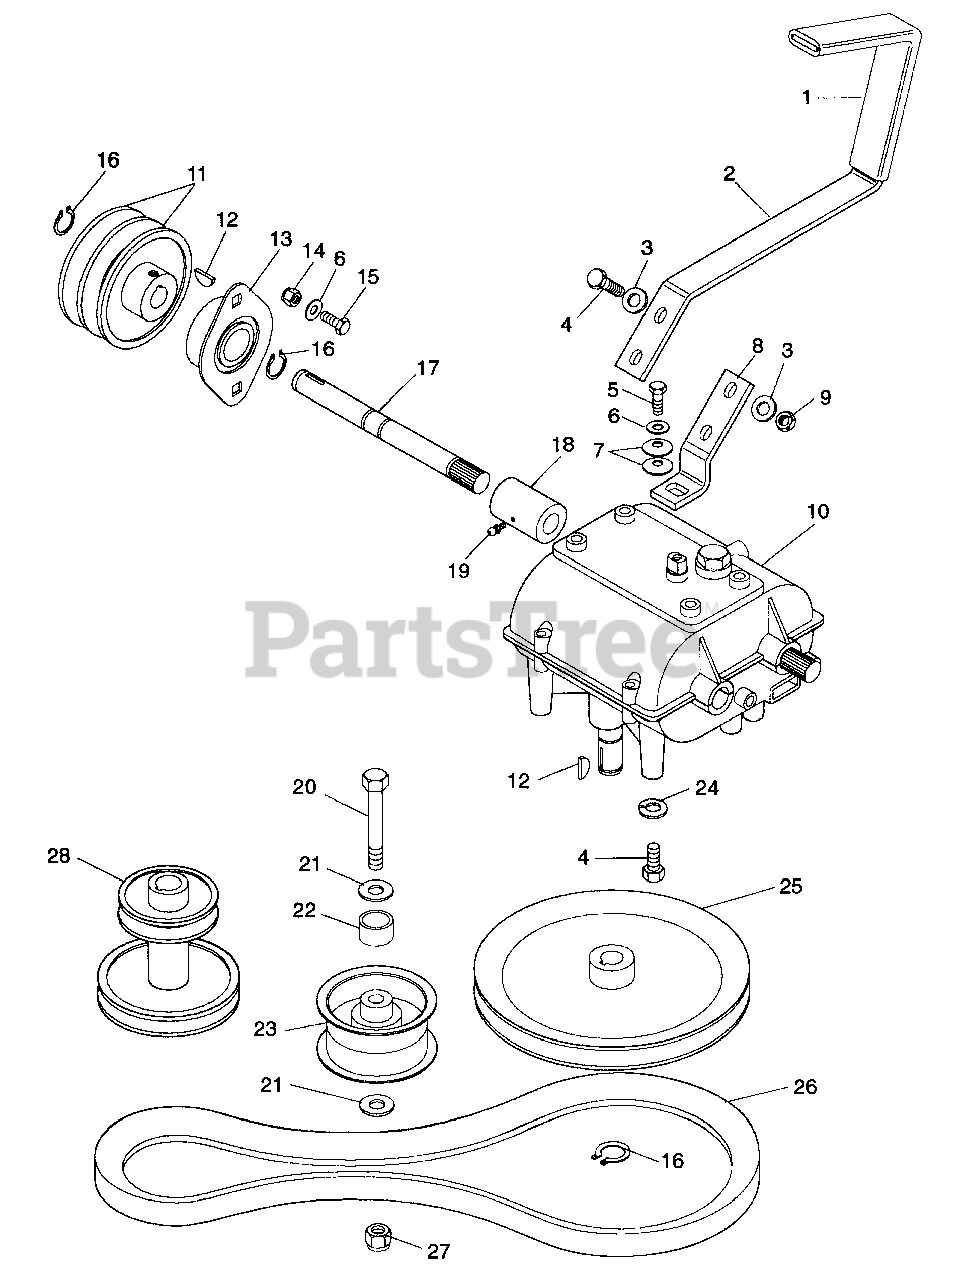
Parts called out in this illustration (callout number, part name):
1	Grip
2	Lever, Transmission Shift
3	Washer-Flat-Steel .344 x .688 x .065
4	Bolt-Hex .31-18 x 1.00 Grade 5
5	Bolt-Hex .25-28 x .75 Grade 8
6	Washer-Flat-Steel .281 x .620 x .065
7	Washer, Belleville
8	Arm, Transmission Shift
9	Nut-Locking-Nylon .312-18 Grade 2
10	Transmission, 5-Speed Pro 32
11	Drive Sheave(Upper) - Pro-100
12	Key, Woodruff .19 x .75
13	Bearing-Flange .625 x 1.875 x .797
14	Nut-Locking-Nylon .250-20 Grade 2
15	Bolt-Hex .25-20 x .75 Grade 5
16	Ring-Retaining-External .579 x .93
17	Half Shaft, Transmission, Pro-150
18	Coupler, Transmission Shaft
19	Fitting-Lube .25-28 x .256
20	Bolt-Hex .38-16 x 2.25 Grade 5
21	Washer-Flat-Steel .406 x .812 x .065
22	Spacer, .625 x .385 x .55
23	Idler-Pulley Flat 3.25 x .625
24	Washer-Lock .313 x .078
25	Pulley-V 7.50 x .63
26	V-Belt A-Section 14.9 x 33/64
27	Nut-Locking-Nylon .375-16 Grade 2
28	Crank Sheave-Pro
